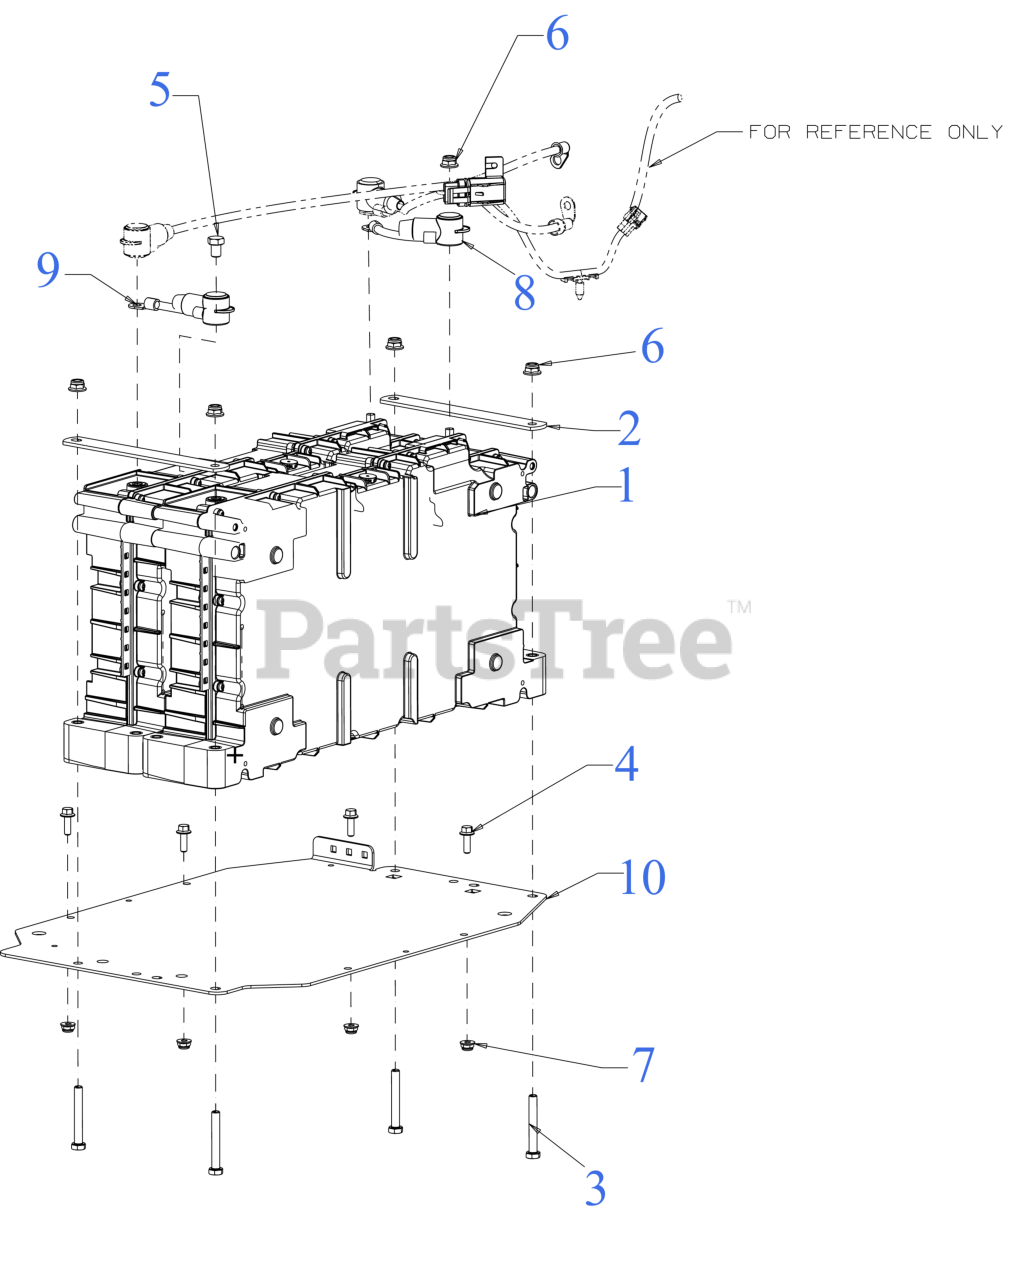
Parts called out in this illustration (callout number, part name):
1	LI-ION BATTERY (48V 30AH 29H)
2	BATTERY MOUNTING PLATE
3	HEX SCREW 5/16-18 x 2.25 GR5
4	SCREW 1/4-20 x .75 GR5
5	SCREW 3/8-24 x .50" GR5 STD
6	FLANGE LOCK NUT 5/16-18
7	FLANGE LOCK NUT
8	JUMPER BATTERY HARNESS
9	JUMPER BATTERY HARNESS
10	BATTERY PLATE BRACKET
